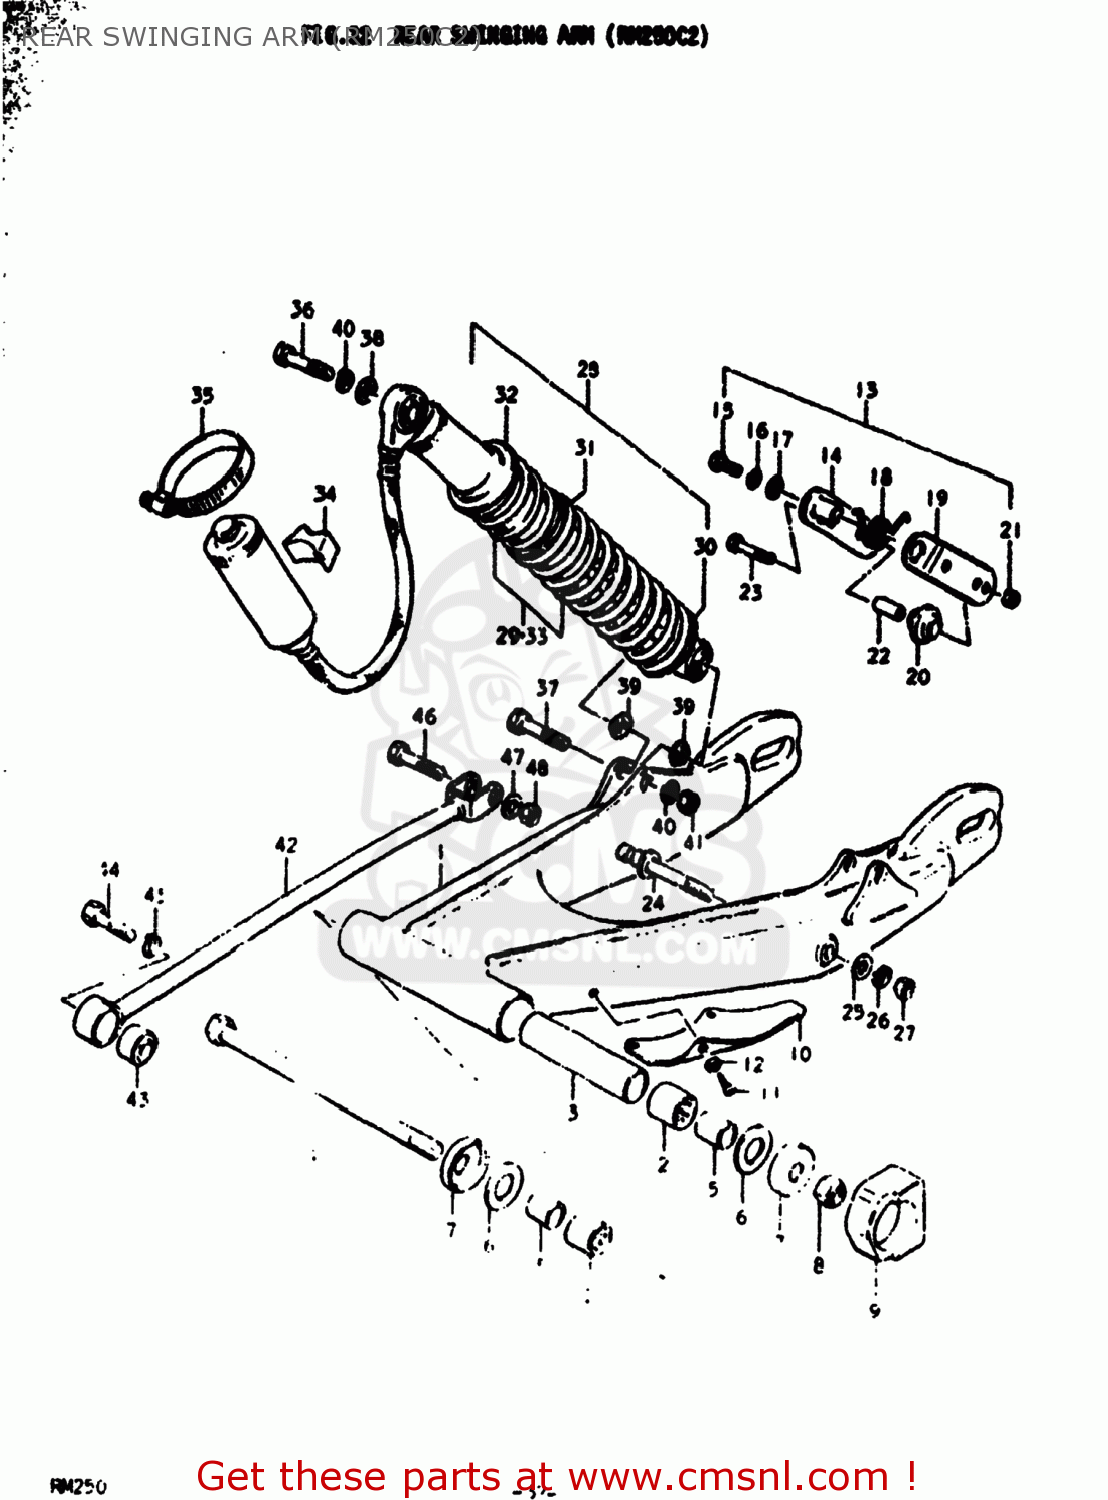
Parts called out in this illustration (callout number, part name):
1	SWING ARM ASSEMBLY,REAR
2	BEARING(22X29X20)
3	SPACER,REAR SWING ARM PIVOT
4	SHAFT,REAR SWING ARM
5	SPACER,RR SWGARM PIVOT
6	WASHER(14.2X34X1)
7	COVER,REAR SWING ARM DUST
8	NUT 14MM
9	BUFFER,CHAIN TOUCH DEFENSE
10	BUFFER,CHAIN TOUCH DEFLECTOR
11	SCREW
12	WASHER
14	TENSIONER,CHAIN
15	BOLT
16	LOCK WASHER
17	WASHER
18	SPRING
19	PLATE,CHAIN TENSIONER
20	RUBBER,CHAIN GUARD
21	NUT 6MM
22	SPACER(6.5X10.5X22.5)
23	BOLT
24	HOLDER,CABLE TENSIONER
25	WASHER
26	LOCK WASHER
27	NUT
28	ABSORBER ASSEMBLY,REAR SHOCK
31	SPRING
32	GUIDE,SPRING
34	CUSHION,RR SHOCK ABSORBER
35	CLAMP
36	BOLT 10X40
37	BOLT(10X48)
38	WASHER
39	WASHER
40	LOCK WASHER
41	NUT
42	LINK,REAR TORQUE
43	BUSH
44	BOLT 10X40
45	LOCK WASHER
46	BOLT 10X40
47	WASHER
48	NUT
